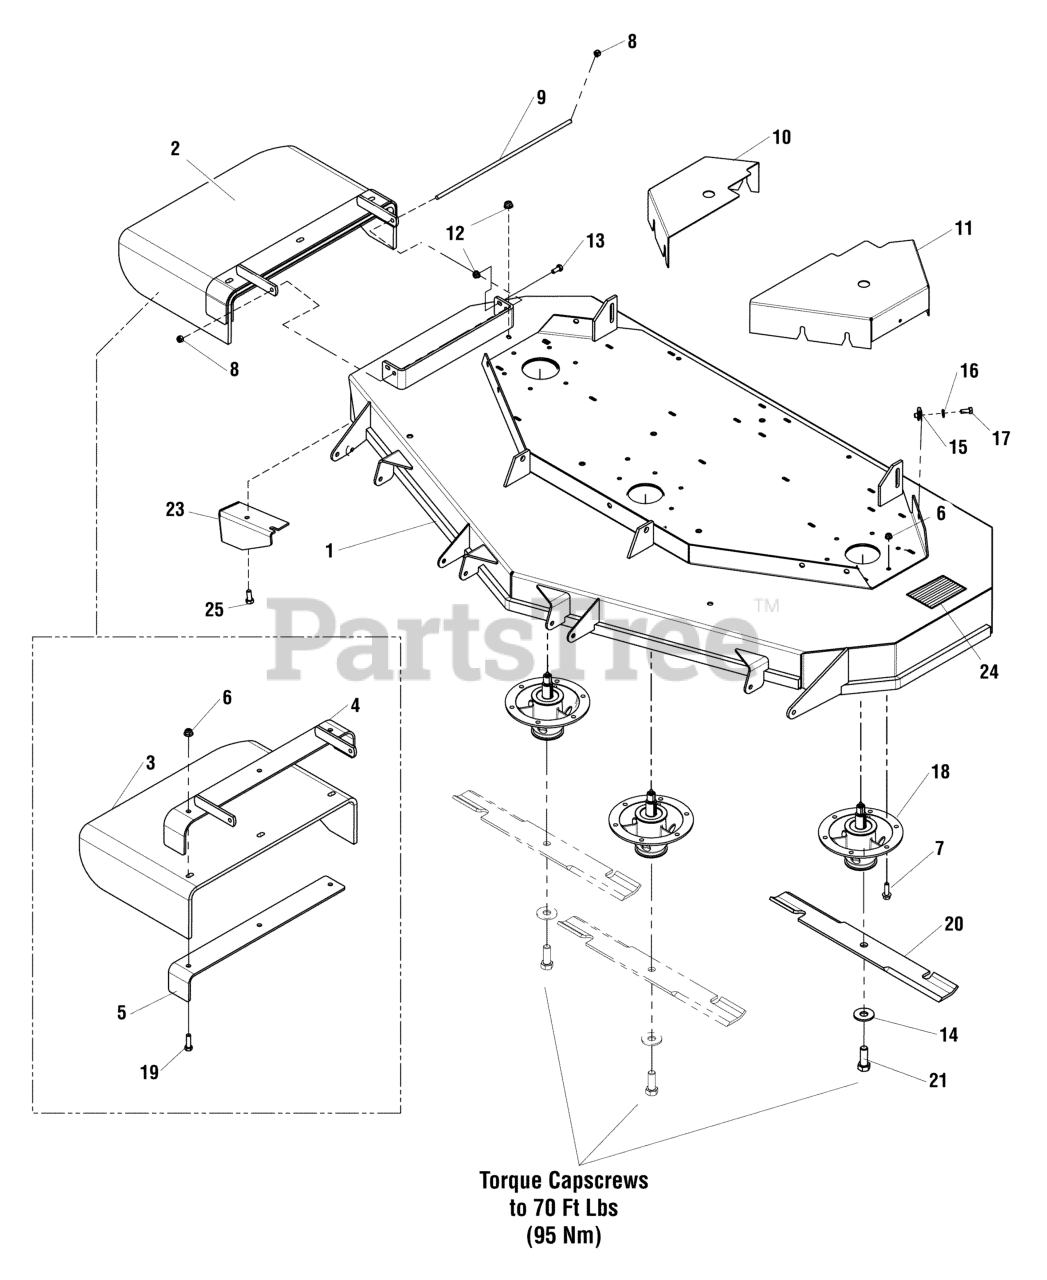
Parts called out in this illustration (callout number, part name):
1	DECK SHELL W/DECALS, 61" SIDE DISCHARGE
2	PURCHASE INDIVIDUAL REPLACEMENT PARTS
3	CHUTE, DISCHARGE, RUBBER, 61/72, BENT
4	WELD, FRAME, CHUTE, 61 - RED
5	SUPPORT, DISCHARGE CHUTE - BLK
6	NUT, 3/8-16 HEX NYLOCK FLANGE
7	BOLT, 3/8-16 X 1" GD5 CZ
8	NUT, 5/16-24 HEX NYLON LOCK
9	ROD MOUNT, CHUTE 61"
10	GUARD, 61", RH - RED
11	GUARD, 61 - LH - RED
12	NUT, 5/16-18 HEX NYLOCK FLANGE
13	BOLT, 5/16-18 X 3/4 GD5
14	WASHER, 5/8" GRADE 8, YZ
15	BODY CLIP, 5/16-18-7GA MATERIAL
16	WASHER, 5/16" SAE
17	BOLT, 5/16-18 X 3/4 GD5
18	ASSM, SPINDLE, CAST IRON
19	BOLT, 3/8-16 X 1-1/2" GD5 CZ
20	BLADE, 21"
21	BOLT, 5/8-11 X 1-3/4 GD8
22	WASHER, 5/16" SAE
23	PLATE, DEFLECTOR - BLK
24	SAFETY WALK, 9.75 X 6.00
25	BOLT, 5/16-18 X 3/4, CARRIAGE
